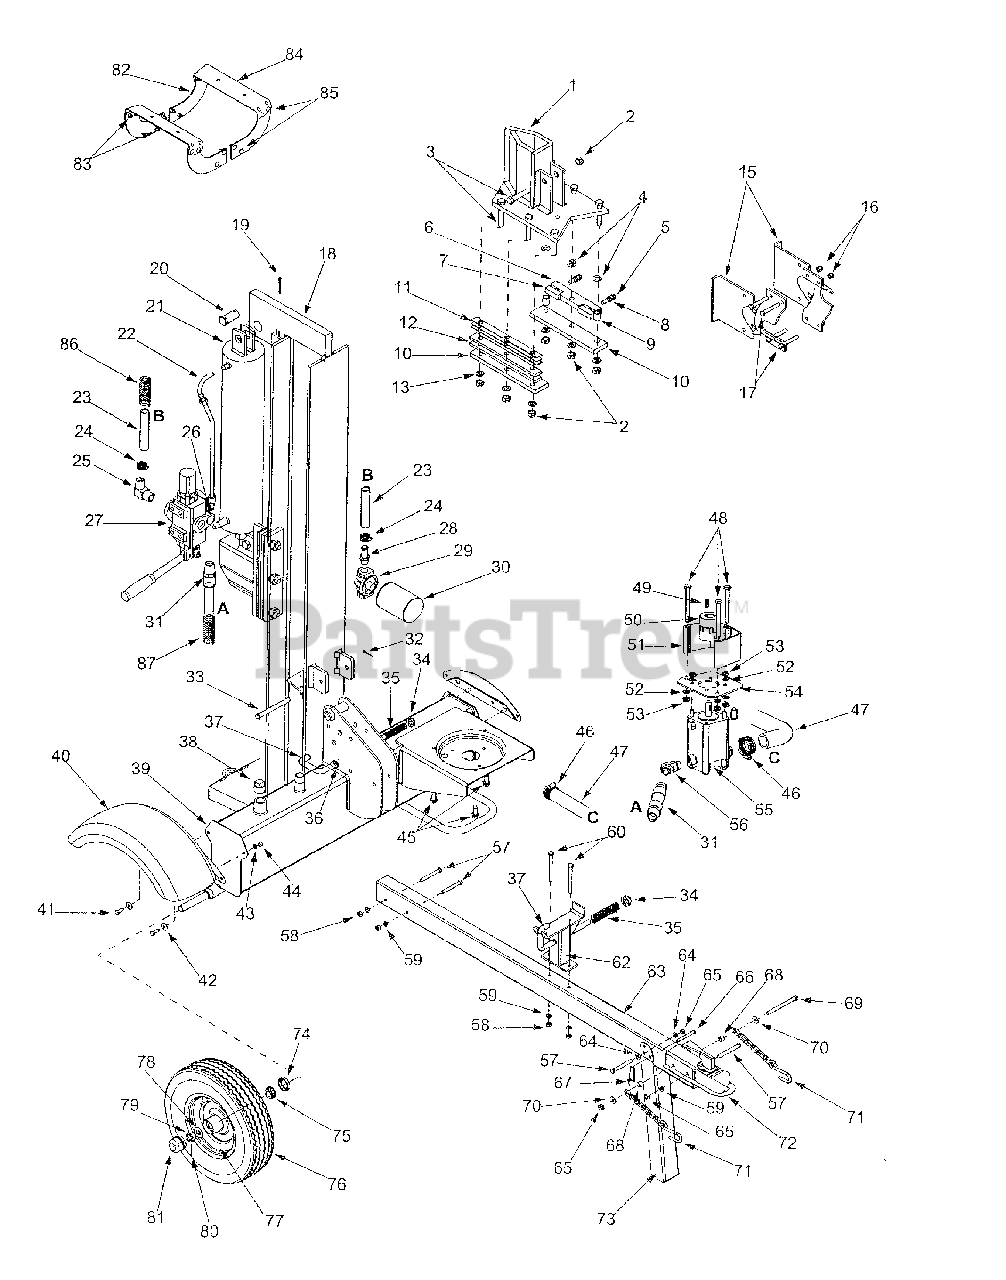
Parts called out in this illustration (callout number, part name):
2	Lock Nut 1/2-20
3	Hex Cap Screw 1/2-20 x 2.75
4	Flat Washer .531 ID x .93 OD
5	Hex Cap Screw 3/8-24 x 1.5
7	Adjustable Gib
8	Hex Jam Nut 3/8-24
13	Lock Washer 1/2
14	Lock Nut 1/2-20
17	Hex Cap Screw 3/8-16 x 2.5
20	Clevis Pin
22	Hydraulic Tube
23	Return Hose 3/4" ID x 44" Lg.
24	Hose Clamp 5/8"
25	Return Elbow
26	90 Degree Solid Adapter
28	3/4" Hose Adapter
29	Filter Housing
30	Oil Filter
31	High Pressure Hydraulic Hose
32	Cotter Pin
33	Hinge Pin 1/2 x 4.8"
35	Compression Spring 4"
36	Flat Washer .635 ID x .93 OD
37	Locking Rod
38	Pipe Plug
39	Frame Assembly 4.0 Gal
42	Washer 5/16
43	Lock Washer 5/16
44	Hex Nut 5/16-24
45	Hex Washer Screw 3/8-16 x 1.
46	Hose Clamp
47	Suction Hose
48	Hex Screw 5/16-24 x 3.25
49	Square Key 3/16" x .75
50	Flexible Coupling (Stamped L075) .875 x .500 ID
50	Flexible Coupling (Stamped L075) .875 x .437 ID
51	Coupling Shield
52	Lock Washer 5/16" ID
53	Hex Nut 5/16-24
55	Gear Pump (11 gpm)
55	Gear Pump (9.5 gpm)
56	45 Degree Elbow
57	Hex Bolt 3/8-16 x 3"
58	Hex Nut 3/8-16
59	L-Washer 3/8"
60	Hex Bolt 3/8-16 x 4"
64	Flat Washer 3/8
65	Hex Lock Nut 3/8-16
66	Clevis Pin 5/16 x 2.5"
67	Spring Pin
68	Spacer 3/8" ID x .625" OD
69	Hex Bolt 3/8-16 x 4"
70	Flat Washer 3/8" ID x .87" OD
71	Chain
72	Hitch Coupler
75	Bearing Cone
76	Wheel Assembly
78	Flat Washer .76" ID x 1.5" OD
79	Slotted Nut 3/4-16
80	Cotter Pin 5/32" x 1-1/4"
85	Carriage Bolt 3/8-16 x 1.0
86	Hose Guard
87	Hose Guard
